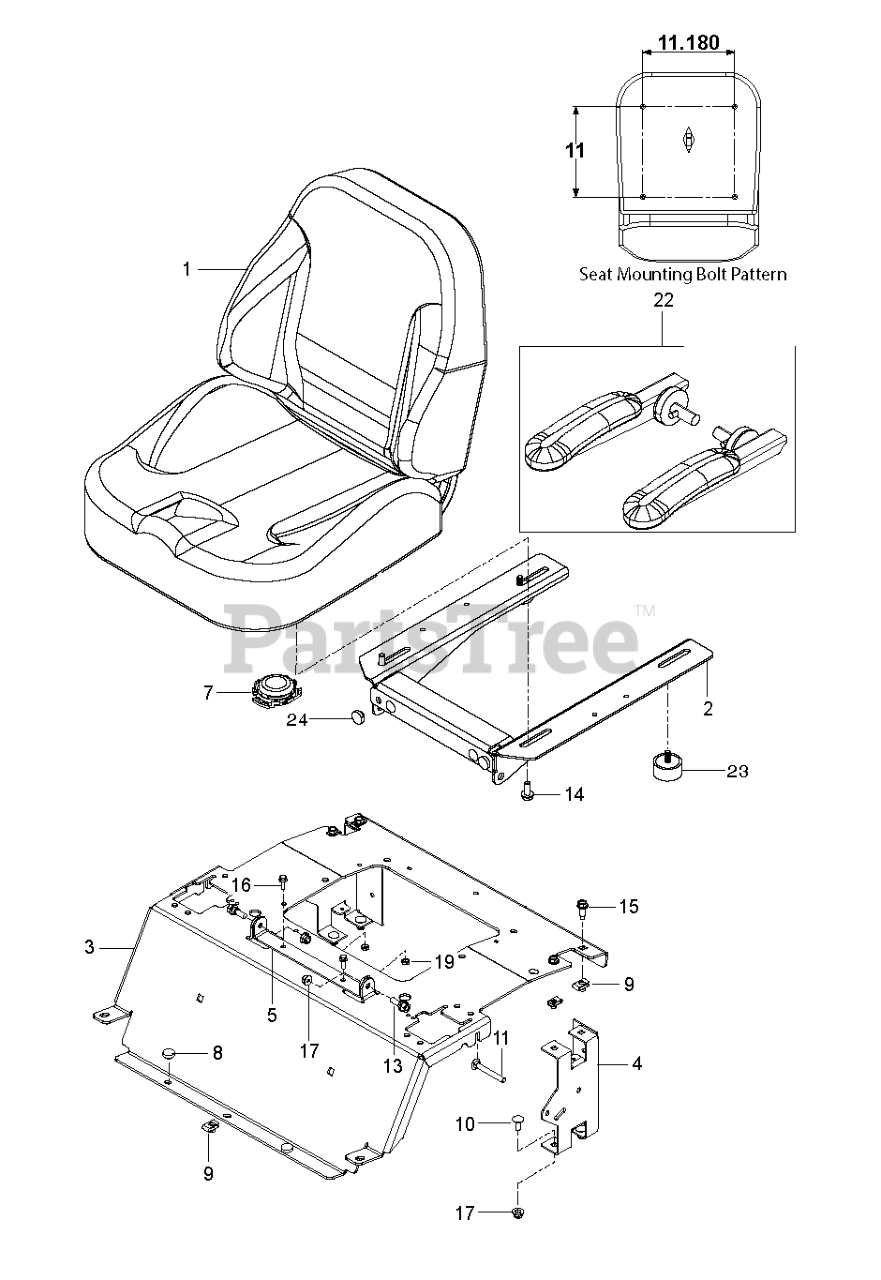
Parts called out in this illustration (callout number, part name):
2	Seat pan
3	PLATE SEAT SUPPORT; RZ SNAPPER
4	SUPPORT REAR SEAT BLACK
5	BRACKET.SEAT.REINF.X672
7	SWITCH, SEAT N/C
8	GROMMET.BUMPER
9	U-CLIP 5/16-18 NUT RETAINER
10	BOLT 5/16C X 3/4" CARRIAGE
11	RHSNB 5/16-18 X 2-1/2 GR5 ZD
13	BOLT SHOULDER 5/16-18 UNC
15	SCREW
16	SCREW.FLG.LOCKING.1/4-20X.75
17	5/16-18 NYLOC FLANGE NUT
19	NUT
22	SEAT KING 18" WOOD BTM, ARM
23	BUMPER 5/16-18 CLEAR ZINC
24	GROMMET, BUMPER
